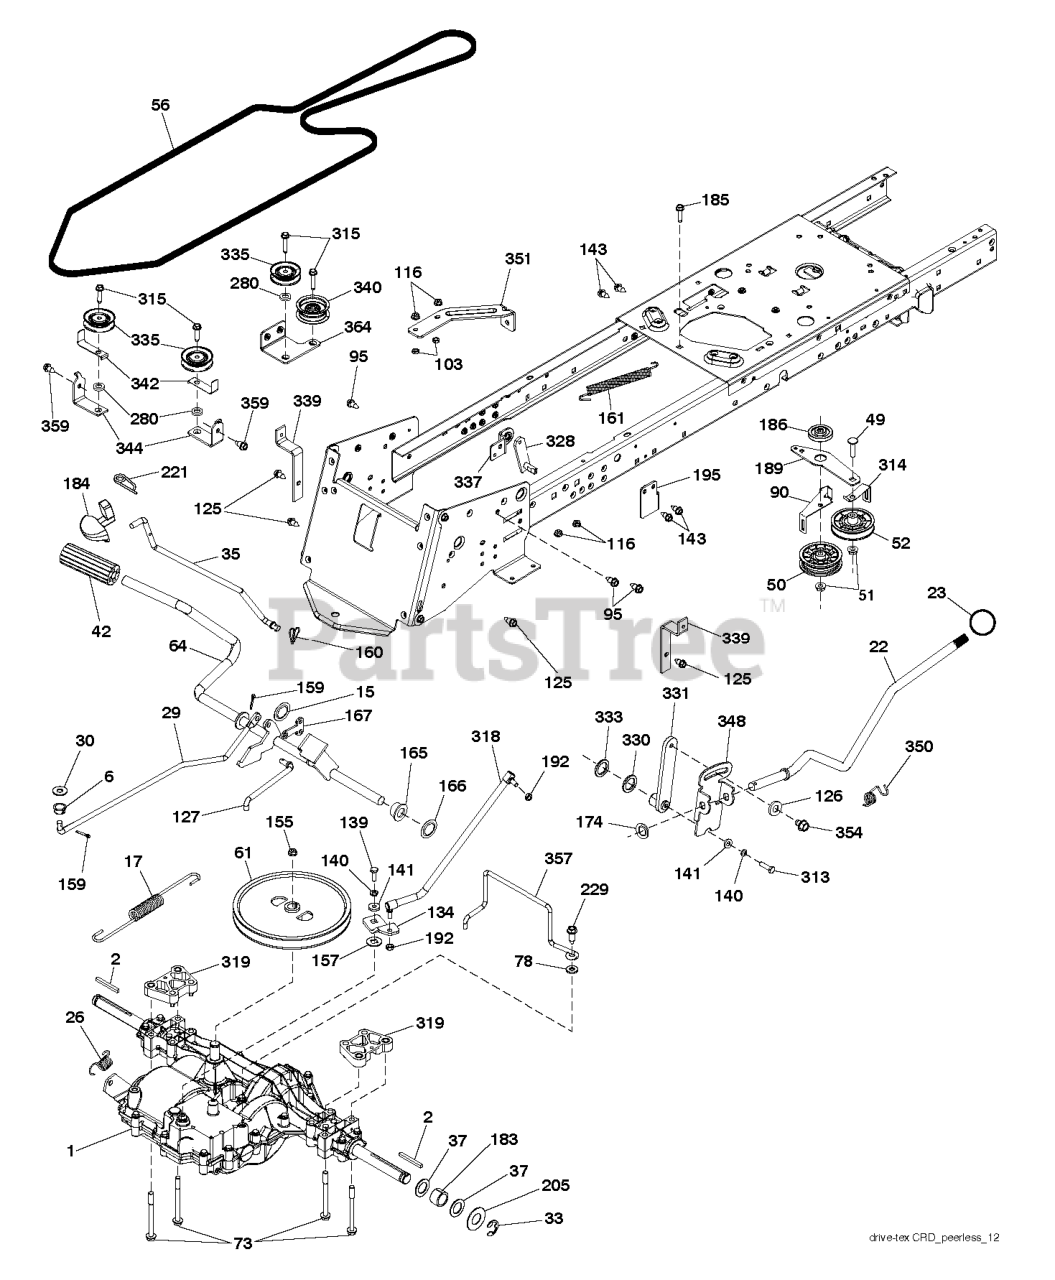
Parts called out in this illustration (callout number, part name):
2	SQUARE KEY
6	BUSHING.SNAP.NYL.BLK.
15	WASHER
17	SPRING SPRING BRAKE GEAR CRD
22	ROD ROD SHIFT FENDER
23	KNOB.DUCKHEAD.1/2
26	SPRING,BRAKE RETURN
29	ROD.BRAKE.GEAR.CRD.TEX
30	WASHER
35	ROD.CNTRL.PARK.PREDATOR.LT.TEX
42	PEDAL COVER T
50	IDLER.FLAT.910.OFFSET
51	NUT LOCK FLG 3/8-16 UNC
52	IDLER.V-GROOVE.910.OFFSET
56	BELT BELT V CRD GEAR
61	PULLEY
64	SHAFT.ASM.PEDAL.BRAKE.
73	BOLT.FLANGED
90	KEEPER KEEPER BELT CLUTCHING T
95	SCREW, 3/8-16X3/4
103	JAM NUT TI
116	NUT LOCK HEX FLANGE 5/16-18
125	SCREW
126	WASHER.SRRTD.5/16
127	RP.LINK.CLUTCH.GROUND.DRIVE
139	BOLT 1/4-28X3/4
140	LOCKWASHER
141	WASHER LT
143	SCREW LT
155	RETAINING RING LT
157	WASH-SHFT PLT LT
159	COTTER PIN
160	RETAINER CLIP
161	SPRING, RETURN LT
165	BUSHING.SHAFT.BRAKE.HAND
166	NUT.PUSH.625
167	LATCH.BRAKE.SPRING
174	NUT.PUSH.500.2006
183	SPACER AXLE
184	HANDLE.PARKING.BRK.PRED.LT.RED
186	SPACER.RETAINER
189	BELLCRANK BELLCRANK GROUNDDRI
192	NUT LOCK CENTER 1/4 -28 FNTHD
221	RETAINER.SPRING.CLIP.H
229	SCREW 5/16-18X1
280	WASHER T
313	BOLT
314	RETAINER KEEPER BELT
315	BOLT.5/16-18X1.25
318	GEAR LINK SHIFT GEAR
319	SPACER SPACER TRANSAXLE TEX C
328	SHAFT SHAFT SHIFT FRONT
330	WASHER.NYL.7/8IDX.105"HYD CR
331	HUB HUB SHIFT FENDER
333	WASHER.WAVE.SPRING
335	PULLEY.V-IDLER.
337	BRACKET BRACKET SUPT SHIFT CR
339	STRAP STRAP TORQUE K46 CRD TE
340	IDLER.FLAT.2.25.INCH
342	BELT GUIDE
344	BRACKET BRACKET IDLER CRD TEX
348	ARM ARM CLEVIS ROD SHIFT TEX C
350	TORSION SPRING SPRING TORSION
351	BRACKET BRACKET DECK SWAY
354	CAPSCREW.HXHD.FLG.5/16-18X.625
357	KEEPER KEEPER
359	SCREW LT.3/8-46X5/8
364	BRACKET BRACKET IDLER CRD TEX
